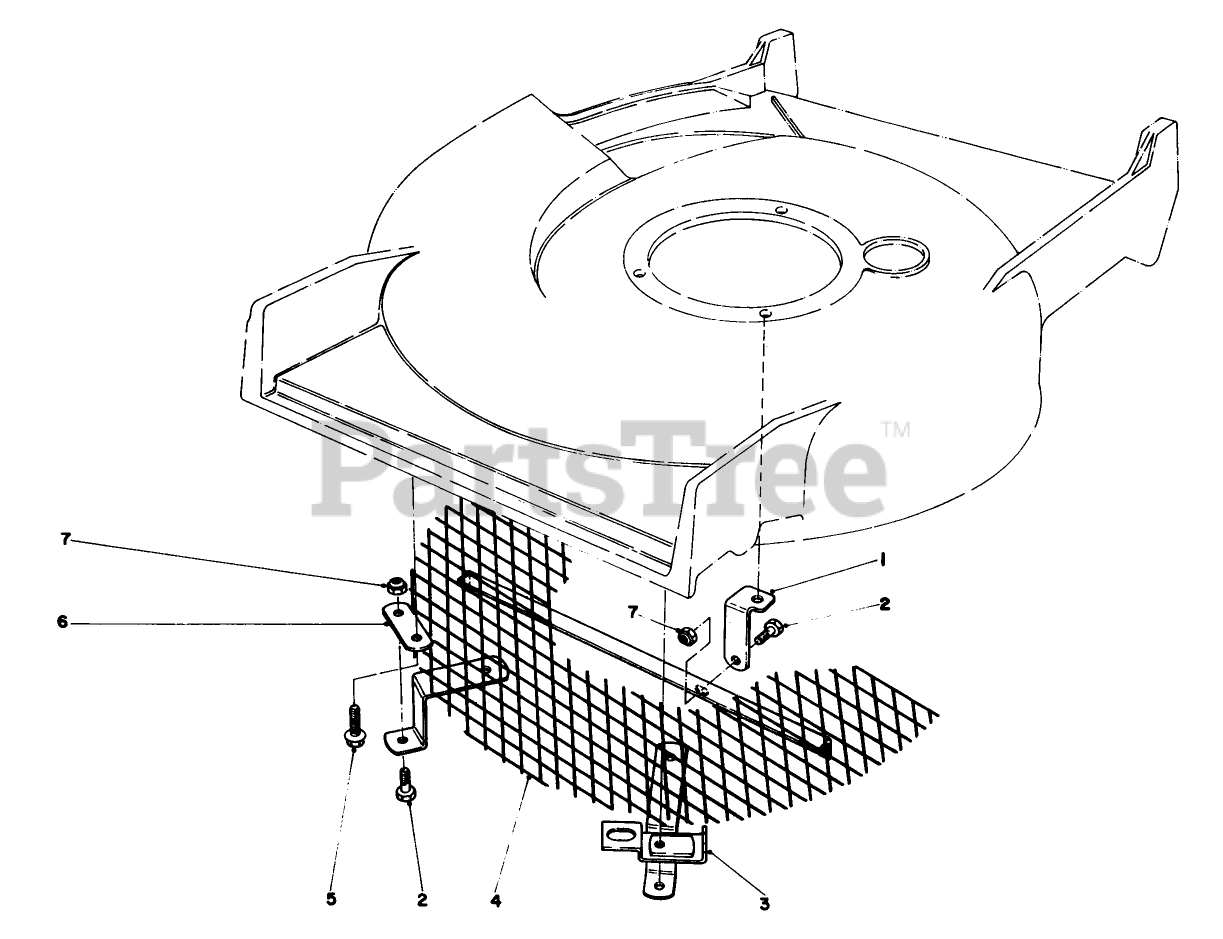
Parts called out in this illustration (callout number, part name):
1	Support Bracket
2	SCREW-HH
3	MTG. BRACKET W.A.
4	Screen
5	SCREW-HWHTF
6	ANCHOR
7	NUT-LOCK, NI
